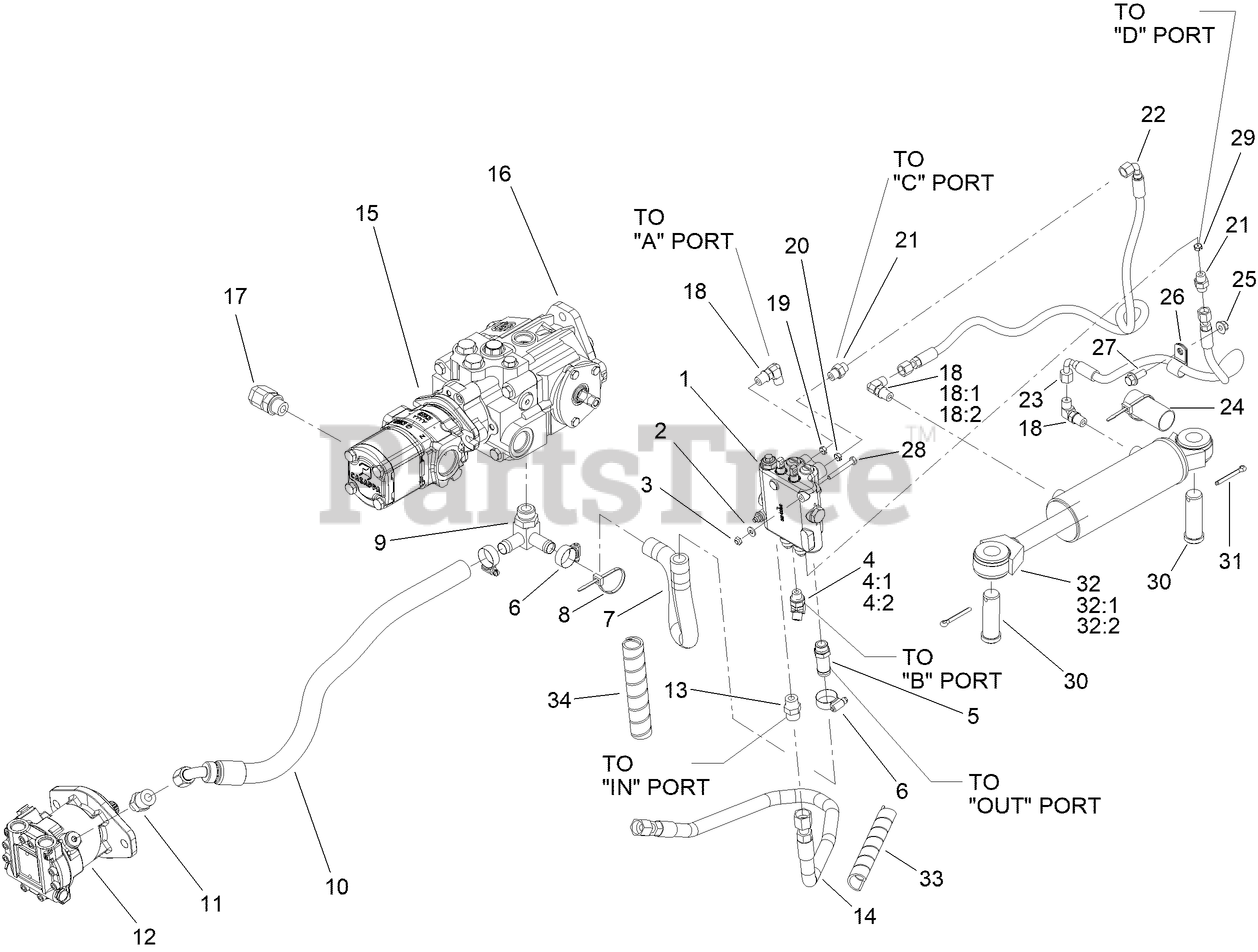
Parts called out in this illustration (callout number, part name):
1	HYD STEERING VALVE ASM
2	WASHER-FLAT
3	NUT-LOCK, CONE
4:1	O-RING
4:2	O-RING
5	S/O COUPLER
6	CLAMP-HOSE
7	HOSE-RETURN 3/4
8	TIE-CABLE
10	HOSE (10FFORX, -12HOSE - 29"-E-Z-FORM)
11	CONNECTOR (08S-10O)
12	HYDRAULIC MOTOR (MP1 24CC)
13	CONNECTOR (08S-08O)
14	HOSE (08OFX-28.5"-3000)
15	PUMP TANDEM (1.29/.44 CIR)
16	HYD VARIABLE PUMP ASM
17	CONNECTOR (08O-10S90)
18	FITTING-ELBOW, 90 DEG
18:1	O-RING
18:2	O-RING
19	ORIFICE
20	PLATE-ORIFICE
21	CONNECTOR (04O-06S)
22	HOSE (04OFX90S-40"-3000)
23	HOSE (04OFX90M-29"-3000)
24	ABRASION SLEEVE (1.25" X 25")
25	NUT-HF, NI
26	CLAMP-R
27	SCREW-HHF
28	SCREW-HH
29	PLATE-ORIFICE
30	PIN-CLEVIS
31	3/8-24 X 1/2 ALLEN SC
32	HYD CYLINDER ASM
32:1	GLAND SEAL KIT
32:2	PISTON SEAL KIT
33	WRAP-SPIRAL [3/4"]
34	WRAP-SPIRAL [1"]
